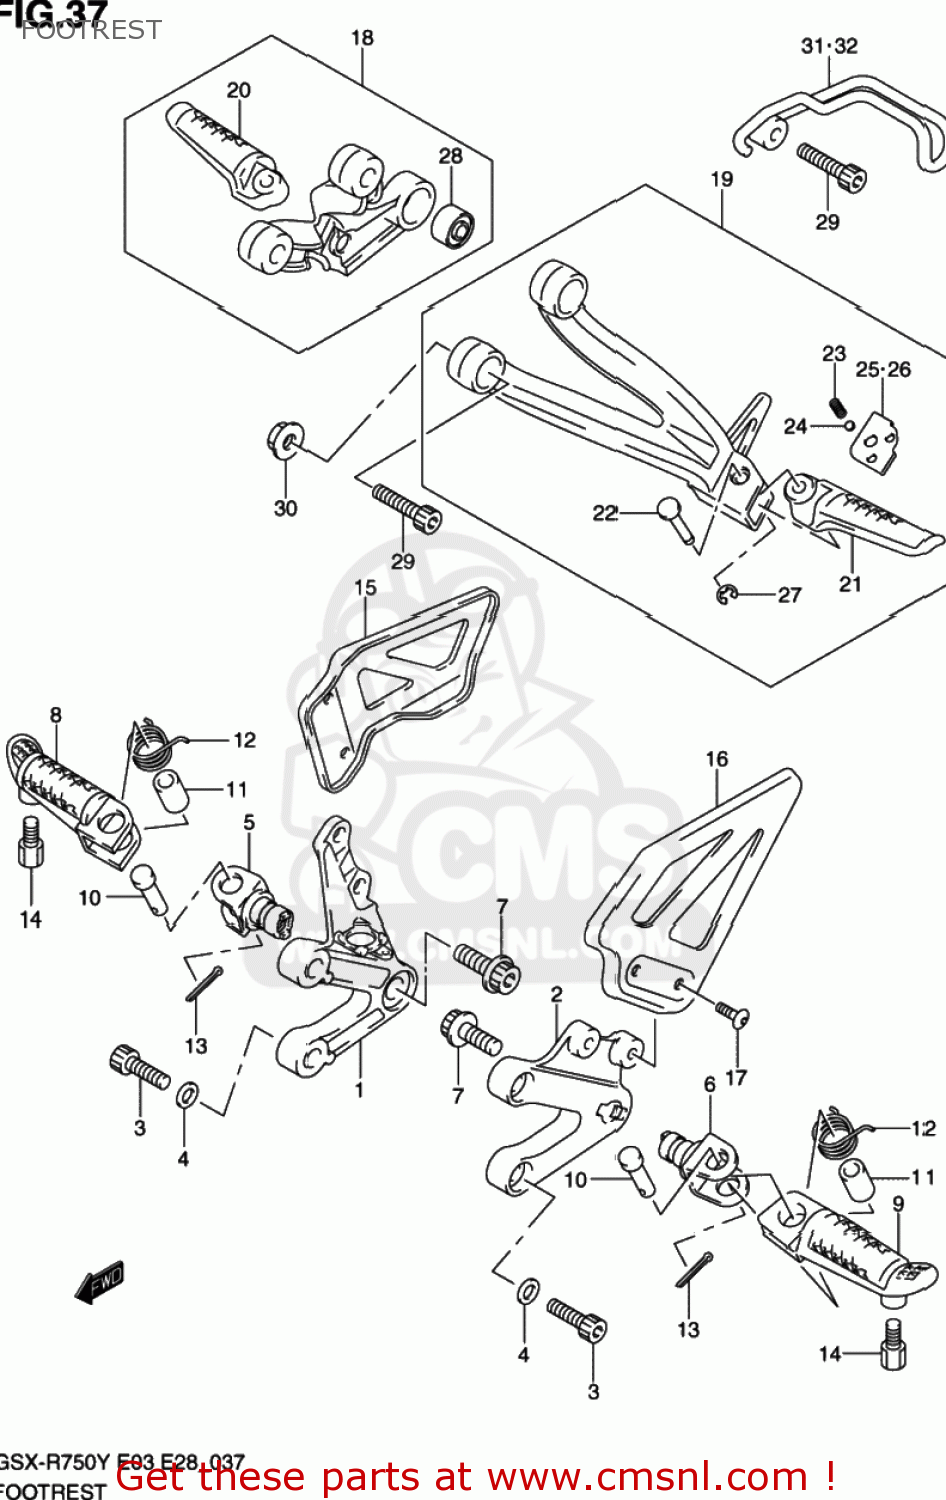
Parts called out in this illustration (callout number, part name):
1	BRACKET,FR FOOTREST,R
2	BRACKET,FR FOOTREST,L
3	BOLT,FOOTREST BRACKET
4	WASHER
5	HOLDER,FOOTRES
6	HOLDER,FOOTRES
7	BOLT(10X28)
8	BAR,FR FOOTREST,R
9	BAR,FR FOOTREST,L
10	PIN
11	SPACER(8.1X12X22)
12	SPRING
13	PIN 20X15
14	BOLT,BANK SENSOR
15	GUARD,FR FOOTREST,R
16	GUARD,FRONT FOOTREST,LEFT
17	SCREW(5X10)
18	FOOTREST ASSY,PILLION,R
19	FOOTREST ASSY,PILLION,L
20	BAR,PILLION FOOTREST,RIGHT
21	BAR,PILLION FOOTREST,LEFT
22	PIN
23	SPRING
24	BALL
25	PLATE,PILLION FOOT,R
26	PLATE,PILLION FOOT,L
27	E-RING
28	BUSH
29	BOLT
30	NUT
31	BRACKET,LUGGAGE HOOK,R
32	BRACKET,LUGGAGE HOOK,L
